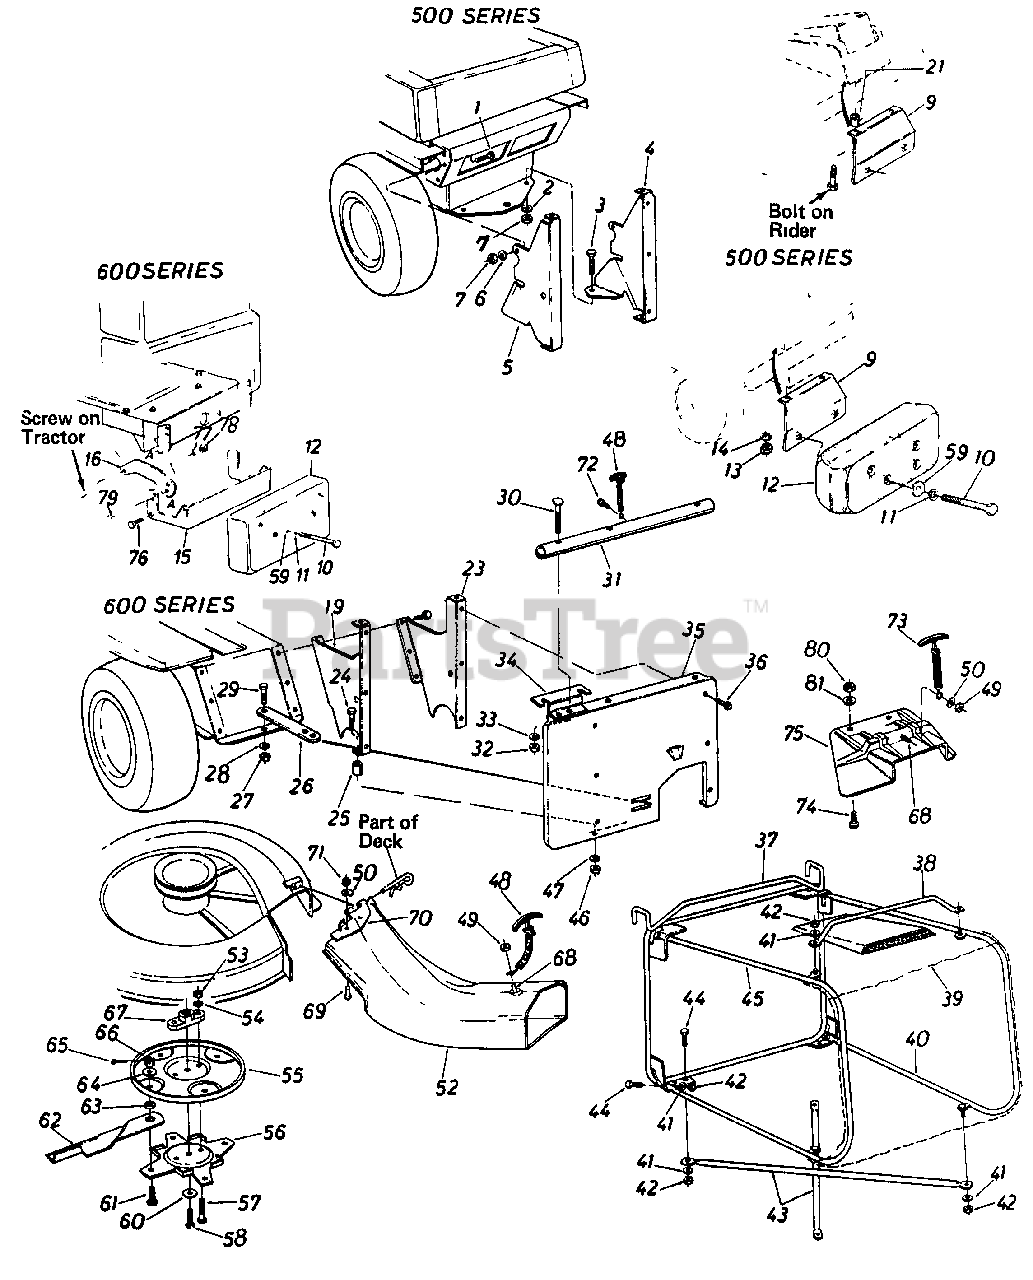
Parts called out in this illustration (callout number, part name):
1	Hex Bolt 5/16-18 x 1.0" Lg.*
2	L.-Wash. 5/16" I.D.*
3	Hex Bolt 5/16-18 x 1.0" Lg.*
4	Catcher Support Brkt-R.H.
5	Catcher Support Brkt-L.H.
6	L.-Wash. 5/16" I.D.*
7	Hex Nut 5/16-18 Thd.*
9	Counterweight Support Brkt. Ass'y
10	Hex Bolt 3/8-16 x 4.5" Lg.*
11	Belleville Wash. .40" I.D. x .88" O.D.
12	Counterweight 38 Ibs.
13	Hex Nut 5/16-18 Thd.*
14	L.-Wash. 5/16" I.D.*
15	Counterweight Support Brkt. Ass'y.
19	Catcher Support Brkt.-L.H.
21	Spacer .380" I.D. x 1.0" O.D. x .32" Lg.
23	Catcher Support Brkt.-R.H.
24	Hex Bolt 5/16-18 x 1.50" Lg.*
25	Spacer .380" I.D. x .47" O.D. x 1.0" Lg.
28	L.-Wash. 1/2" I.D.*
29	Hex Bolt 1/2-20 x 1.0" Lg.*
30	Curved Carriage Bolt 5/16-18 x 1.75" Lg.
33	L.-Wash. 5/16" I.D.*
34	Grass Catcher Support Plate
35	Rear Discharge Panel
36	Hex Wash. Hd. Self Tap. Scr. 1/4-20 x .50" Lg.
37	Grass Catcher Frame Ass'y.
42	Hex L.-Nut 1/2-20 Thd
43	Bottom Cross Brace
44	Hex Bolt 1./4-20 x .62" Lg.
47	L-Wash. 5/16" I.D.
48	Hook Latch Ass'y.
49	Hex L.-Nut 1/4-20 Thd.
50	Fl.-Wash. 1/4" I.D.*
52	R.D. Banana Chute Ass'y.
53	Hex Nut 5/16-24 Thd.
54	L.-Wash. 5/16" I.D.
55	Upper Blade Disc
58	Hex Bolt 3/8-24 x 1.0" Lg.
59	Fl.-Wash. .39" I.D. x 1.12" O.D.
60	Bell.-Wash. 39" I.D. x 1.38"
61	Shld. Bolt. .50" Dia. x .360 Spec.
62	30" Blade Tip
63	Spacer .505" I.D. x .75" O.D. x 1.25" Lg.
64	Fl.-Wash. .50" I.D. x 1.25" O.D.
65	Cotter Pin 3/32" Dia. x 1.0" Lg.*
66	Hex Sl otted Nut 1 /2-20 Thd.
67	Blade Adapter
68	Hex Bolt 1/4-20 x .50" Lg.*
69	Truss Mach. Scr. 1/4-20 x .50" Lg.
72	Hex AB Tap Scr. 1/4 x .62" Lg.
73	Hook Latch Ass'y. 7" Lg.
74	Truss Mach. Scr. 1/4-20 x 50" Lg.
75	R D Chute Extension
76	Hex Bolt 7/16-20 x 1.0" Lg.*
77	L.-Wash. 7/16" I.D.*
78	Hex Nut 7/16-20 Thd.*
79	Self-Tap. Scr. 5/16-18x 1.0" Lg.
80	Hex L.-Nut 1/4-20 Thd.
81	Fl.-Wash. .281" I.D. x .50" O.D. x .063
